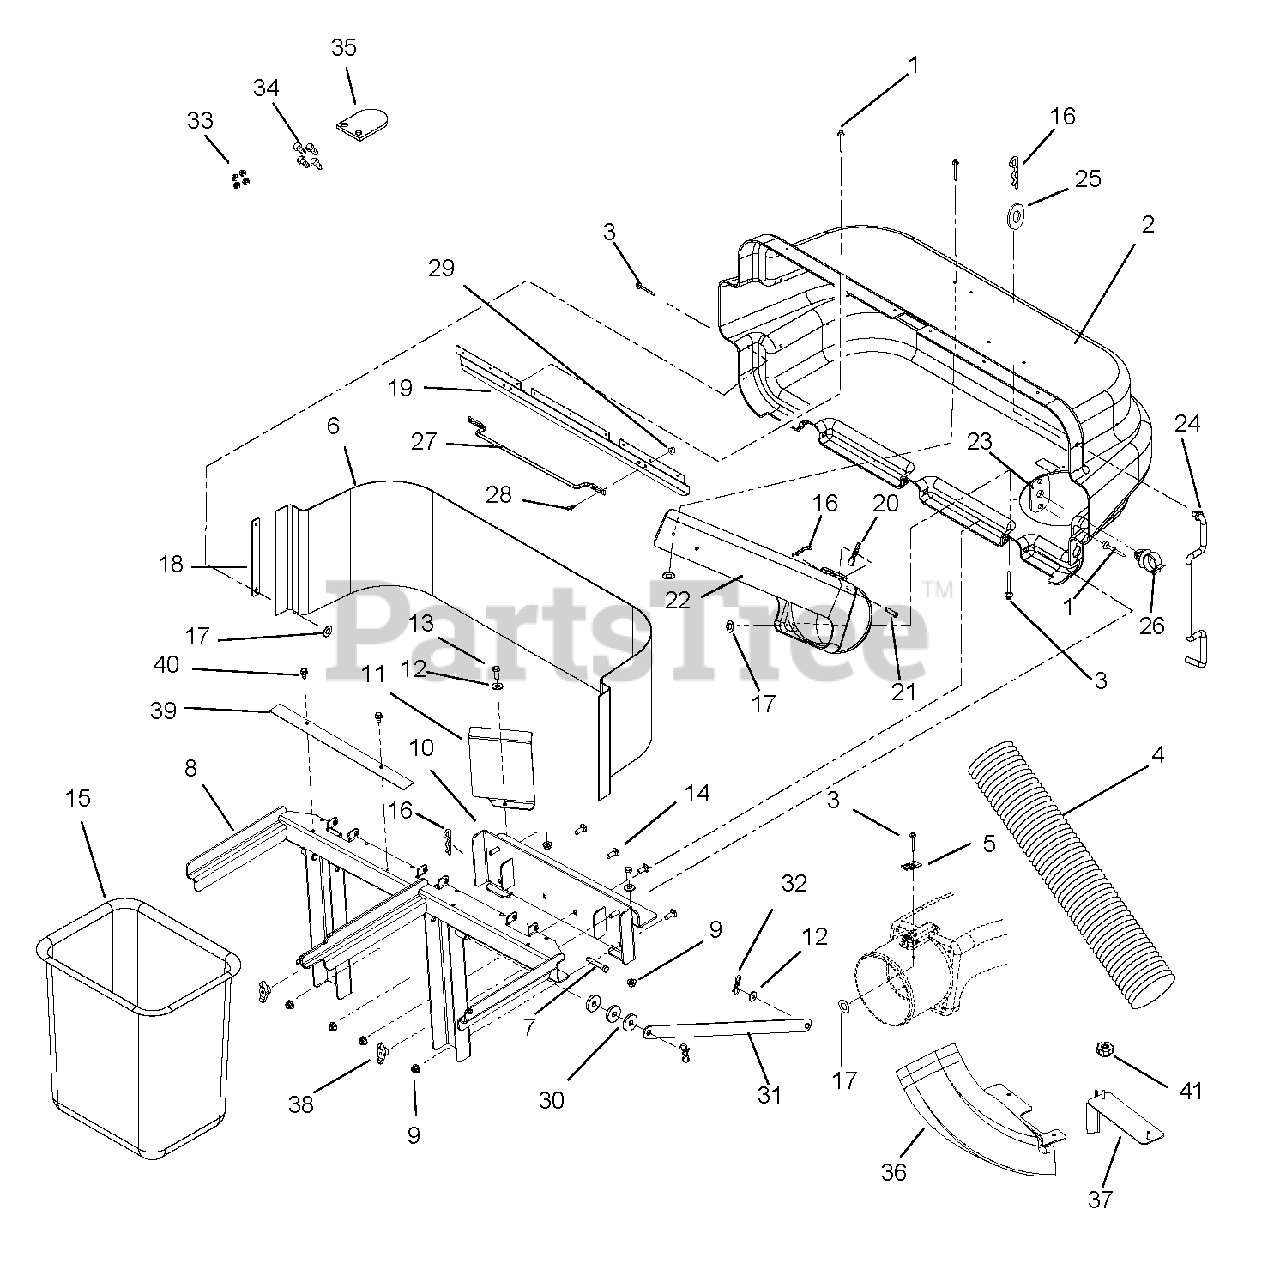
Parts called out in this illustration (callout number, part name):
1	Rivet, Pop .187 x .402
2	Cover, Bagger with Decal
3	Rivet, Pop .187 x .375
4	Hose 7 x 45
5	Thumb Latch
6	Screen, Bagger
7	Pin, Clevis .368/.373 x 3.25
8	Weldment, Bagger Frame
9	Nut, Locking Nylon Flange
10	Weldment, Mounting Plate
11	Deflector, Muffler
12	Washer, Flat Steel .438 x 1.00 x .083
13	Bolt, Hex .38-16 x 1.00
14	Bolt, Round Head Square Neck .38-16 x 1.00
15	Bag, Mesh
16	Pin, Hair
17	Washer, Flat Steel .219 x .50 x .049
18	Strap, Cover
19	Latch, Cover
20	Indicator, Flow
21	Pin, Clevis .31 x 2.62 Grade 5
22	Boot, Upper
23	Plate, Rod Clip
24	Prop, Rod, Bagger
25	Washer, Flat Steel .046 x .812 x .065
26	Clip .38
27	Handle, Bagger
28	Bolt, Round Head Square Neck .25-20 x .75 Grade 5
29	Nut, Locking Top Flange .25-20
30	Washer, Flat .515 x 1.62 x .250
31	Pin, Bow Tie Locking Cotter .091 x 1.875
32	Weldment Strap, Bagger
33	Nut, Center Locking .31-24
34	Bolt, Hex .31-24 x .75 Grade 8
35	Vane, Blade
36	Bagger Boot Assembly, 34-Inch Deck
37	Bagger Boot Mount, 34-Inch Deck
38	Nut, Wing .38-16
39	Bracket, Bagger Overlap
40	Screw, Tapping .31-18 x .50 Hex Washer Head Thread Rolling
41	Knob, Clamping Nyloc .312-18
